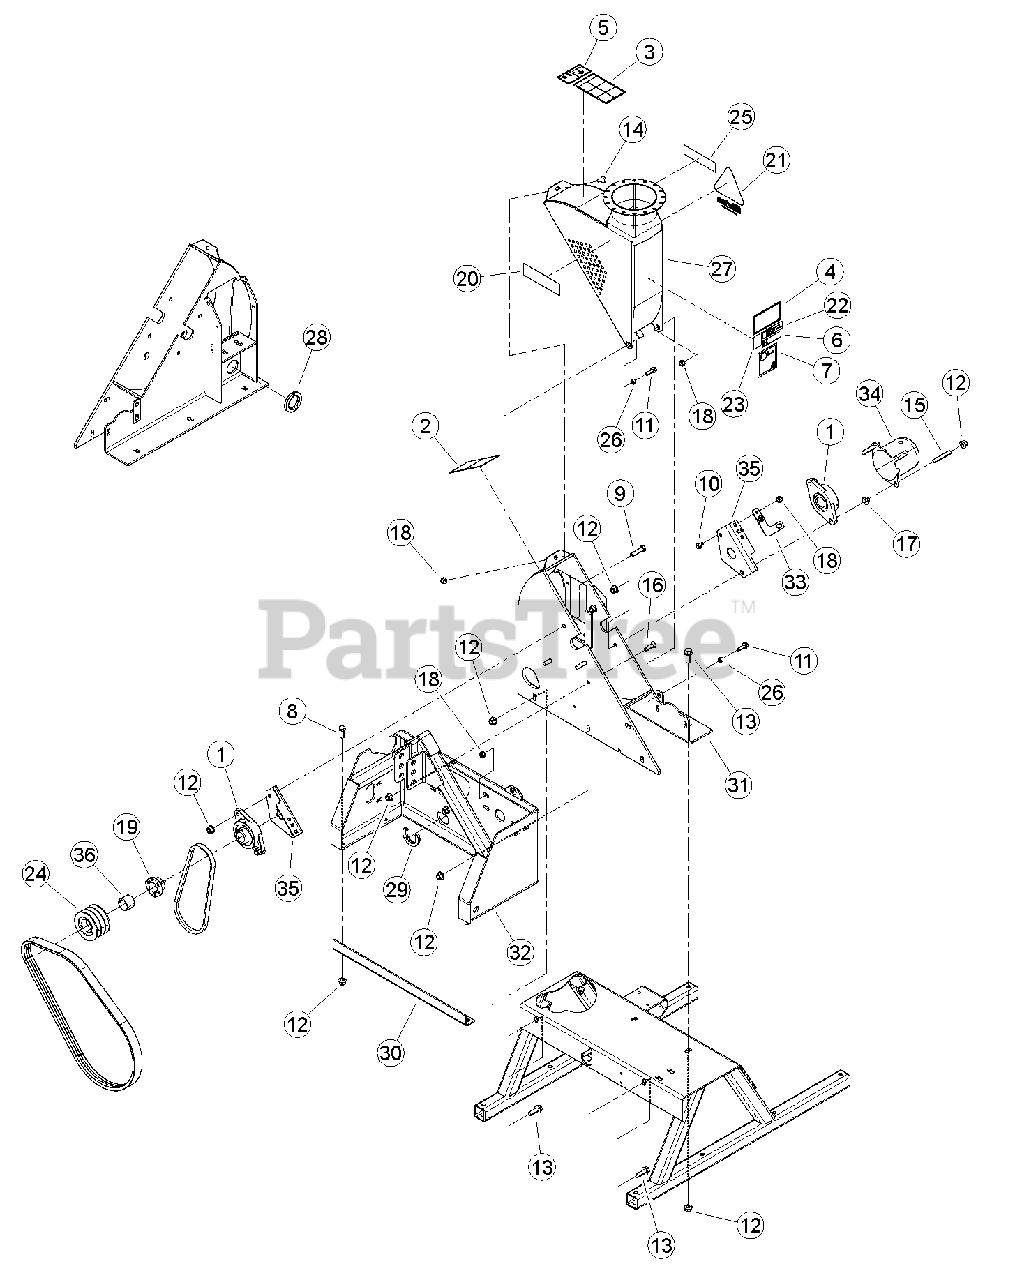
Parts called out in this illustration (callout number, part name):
1	BEARING, 1-1/2" 2-BOLT SET SCREW
2	DECAL, KNIFE ACCESS ISO
3	DECAL, OPERATING INSTRUCTIONS ISO
4	DECAL, DISCHARGE ISO
5	DECAL, MAINTENANCE ISO
6	DECAL, 74554 INFO (CE COMPLIANT ONLY)
7	DECAL, 103 DB (CE COMPLIANT ONLY)
8	BOLT, 1/2 X 1-1/4" GR5 HHCS NC ZP
9	BOLT, 1/2 X 2 GR5 HEX CAPSCREW ZP
10	BOLT, 3/8 X 1" GR5 CRG NC ZP
11	BOLT, 3/8 X 1-1/4 FLANGE NC
12	NUT, 1/2-13 NYLOCK FLANGE
13	BOLT, 1/2-13 X 1-1/2 GR5 FLANGE NC
14	BOLT, 3/8 X 1-1/4" GR5 CRG NC ZP
15	STUD, 1/2"-13 X 3" LG B7 ZP
16	SCREW, 1/2 X 1-1/2 FLT HD SKT
17	NUT, 1/2 SPIRAL LOCK NC ZP
18	NUT, 3/8-16 NYLOCK FLANGE
19	BUSHING, SH 1-1/2"
20	DECAL, ECHO BEARCAT 6.82 X 1.90
21	DECAL, CHIP IT
22	DECAL, ATLANTIC BRIDGE LTD INFO (CE COMPLIANT ONLY)
23	DECAL, ECHO BEARCAT QR CODE
24	SHEAVE, 3B3.8 SH
25	DECAL, MODEL CH5540H
26	BUSHING
27	WELDMENT, CHIPPER TOP
28	TRIM, SLOT EDGE COVER
29	TRIM, SLOT EDGE COVER
30	BRACE, 3 PT BOTTOM
31	WELDMENT, CHIPPER FRAME
32	WELDMENT, CHIPPER HITCH
33	BRACKET, SENSOR
34	CAP, LARGE SHAFT
35	PLATE, BEARING MOUNT
36	SPACER, 1.75 X 1.32 X .120
